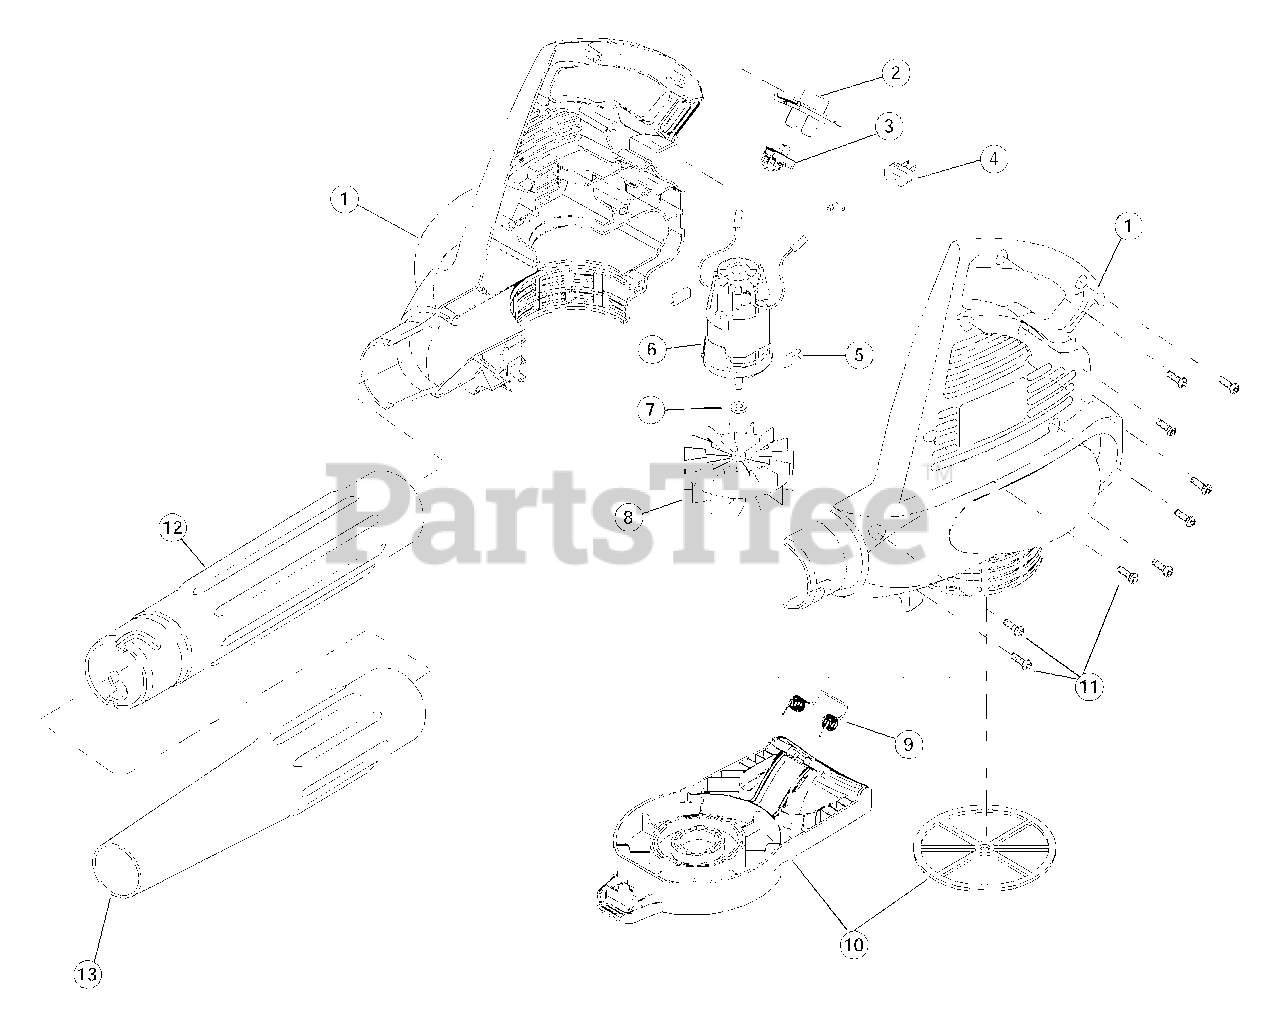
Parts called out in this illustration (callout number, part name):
1	Housing Set
2	Switch Cover (Model 170r, 180r & 190r)
3	Switch (Model 170r, 180r & 190r)
4	Power Cord
5	Motor Pad
6	Motor,
8	Impeller
10	Inlet Cover w/Handle
11	Screw (11 Pack)
12	Blower Tube
